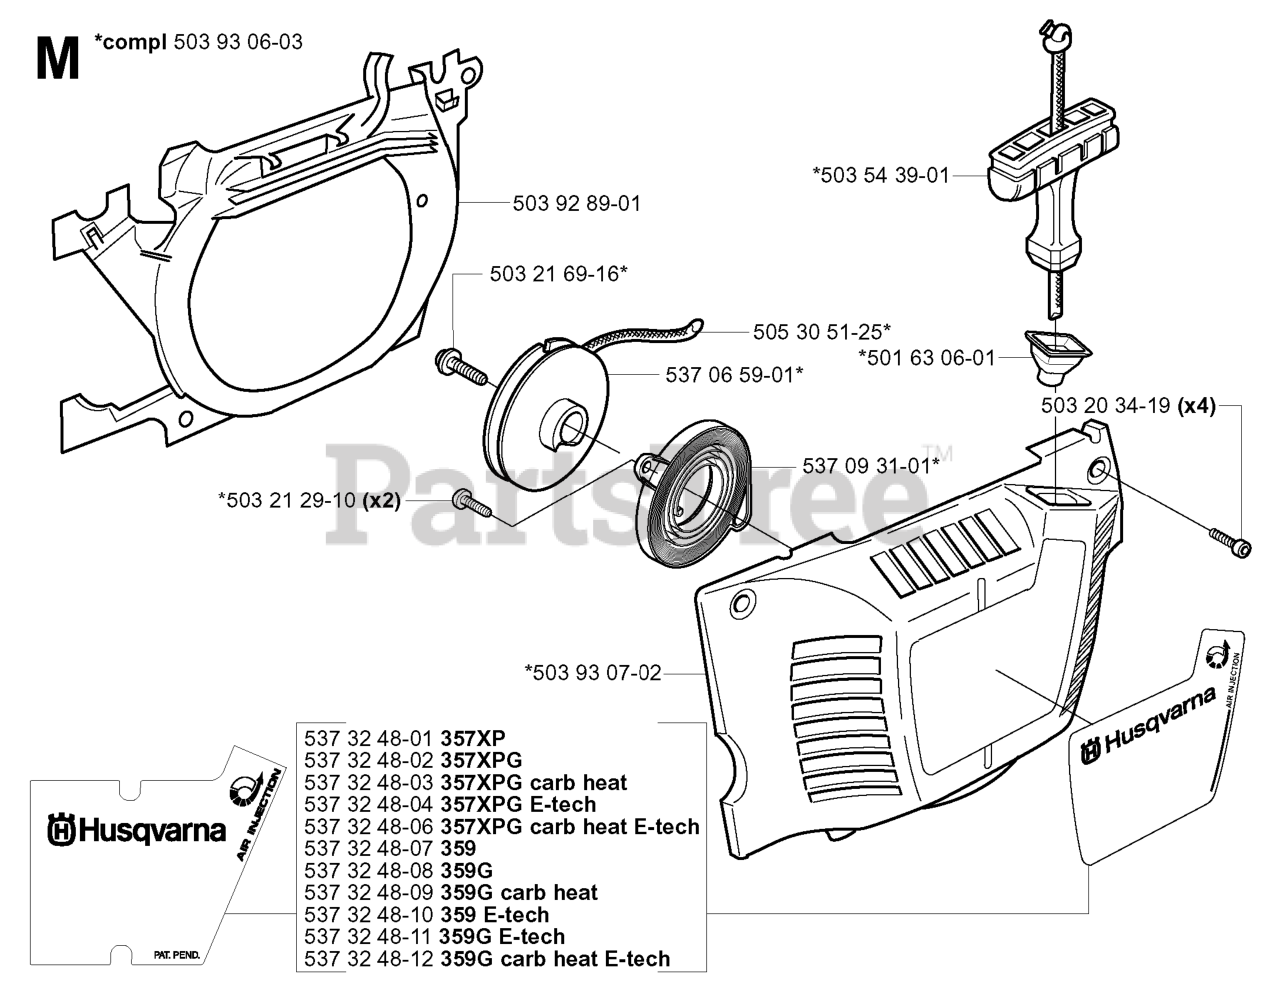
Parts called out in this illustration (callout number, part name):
2	FRAME.WELDMENT.GREY
3	WHEEL.8".GRAY.HUSQ.BUSHING.CEN
4	NUT.PUSH.AXLE.0.5IN
5	SCREW. 5/16-24 X 2.00"HHCS
6	BOLT 3/8-16X1-1/8
7	NUT.HEX.FLANGE.1/4
8	BOLT.CARRIAGE.1/4-20 X 7/8
9	BAR.SCRAPER
10	SPACER.ENGINE
11	LEVER.CHOKE
13	SKIRT.SCRAPPER-SSST
14	SUPPORT SUPPORT.SSST.REAR.FRAM
15	SCREW HEX CRT
